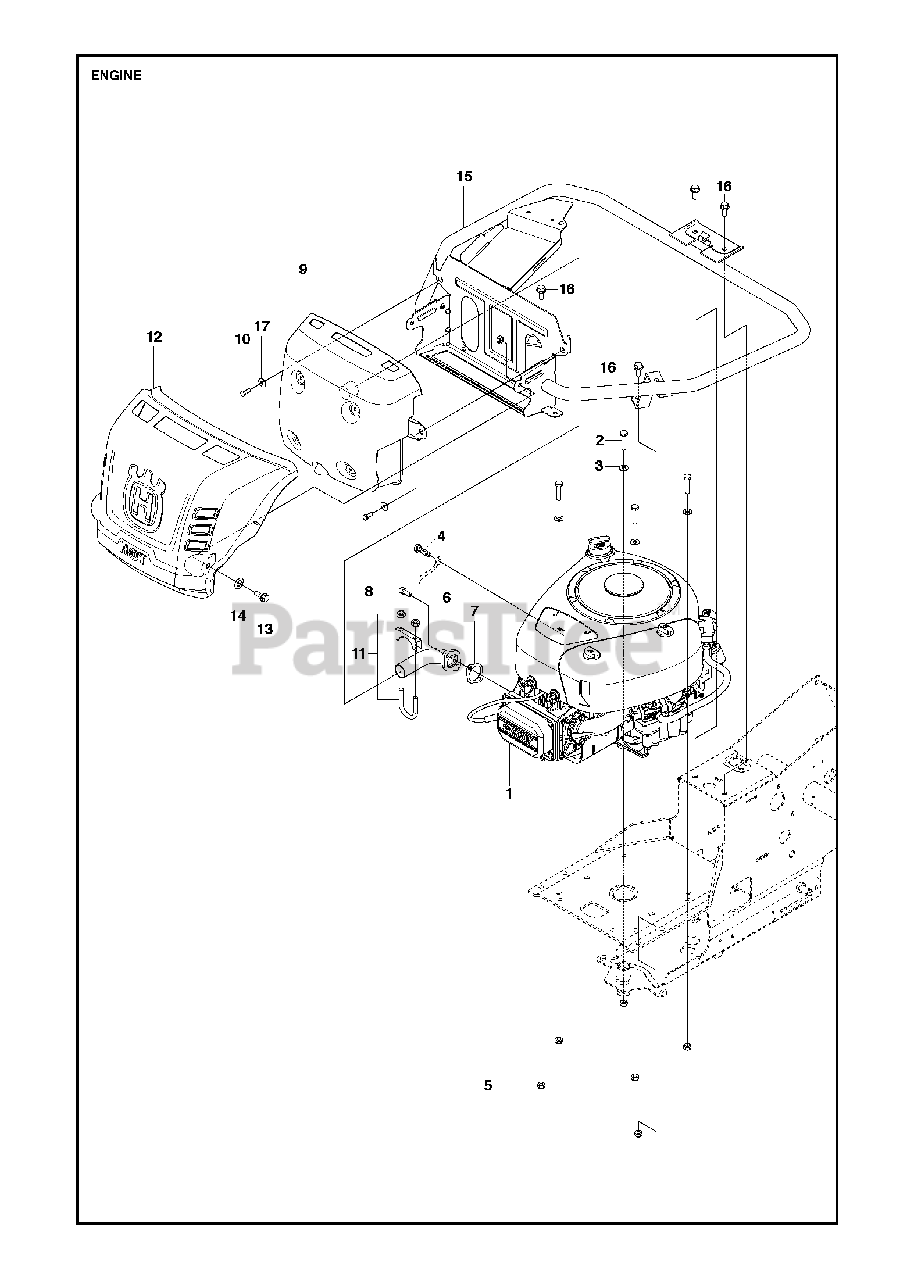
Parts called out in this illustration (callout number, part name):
3	WASHER BRB 8.4X17
5	LOCKNUT M8
11	CLAMP
12	Heat Shield
14	SPRINGWASHER
17	Washer, M6
